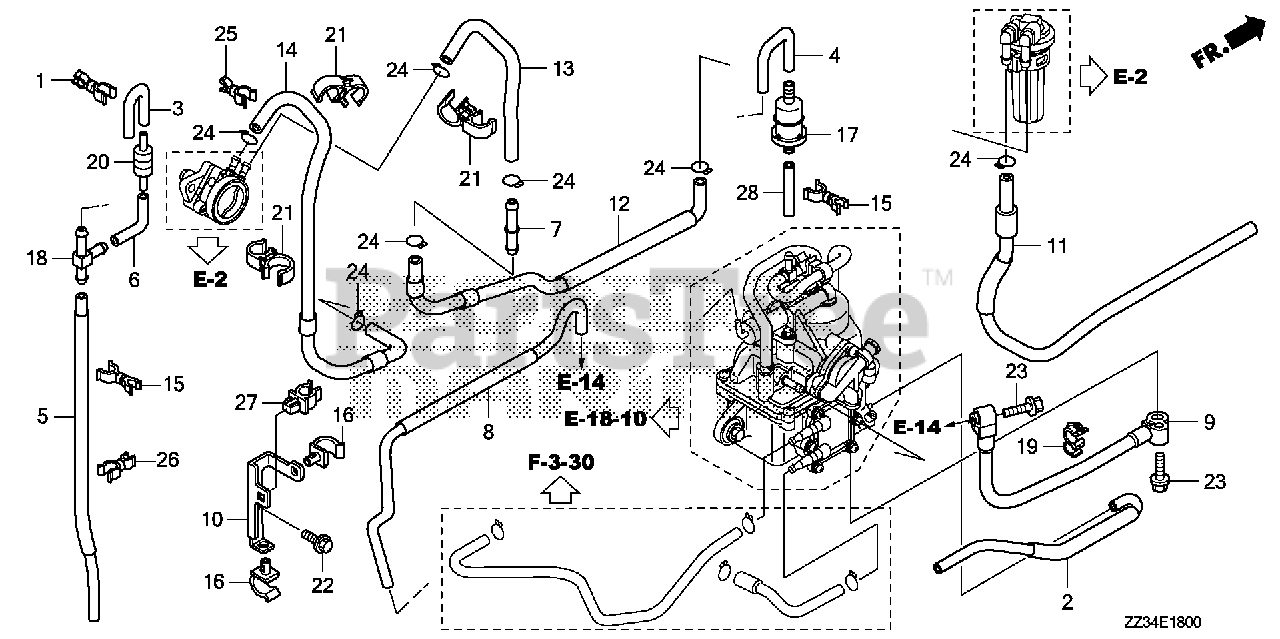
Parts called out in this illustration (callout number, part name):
1	CLAMP, OIL HOSE
2	TUBE, DRAIN
3	TUBE B, CHECK VALVE
4	TUBE C, AIR VENT
5	TUBE D, AIR VENT
6	TUBE E, AIR VENT
7	JOINT, FUEL FEED HOSE
8	TUBE, PRESSURE REGULATOR CONTROL
9	HOSE, FUEL
10	BRACKET, TUBE CLAMP
11	TUBE A, FUEL
12	TUBE B, FUEL
13	TUBE D, FUEL
14	TUBE C, FUEL
15	CLAMP, AIR VENT TUBE
16	CLAMP B, FUEL TUBE
17	FILTER, FUEL
18	JOINT, THREE WAY
19	CLAMP, TUBE (7.5-11.5) (BLACK)
20	VALVE, CHECK
21	CLIP, SENSOR HOSE
22	BOLT, FLANGE (6X14) (CT200)
23	BOLT, FLANGE (6X25)
24	CLIP, TUBE (B12)
25	CLAMP (6MM-12MM)
26	CLIP, WIRE
27	CLIP, TUBE (3.5)
28	BULK HOSE, FUEL (5.5X3000) (5.3X35)
